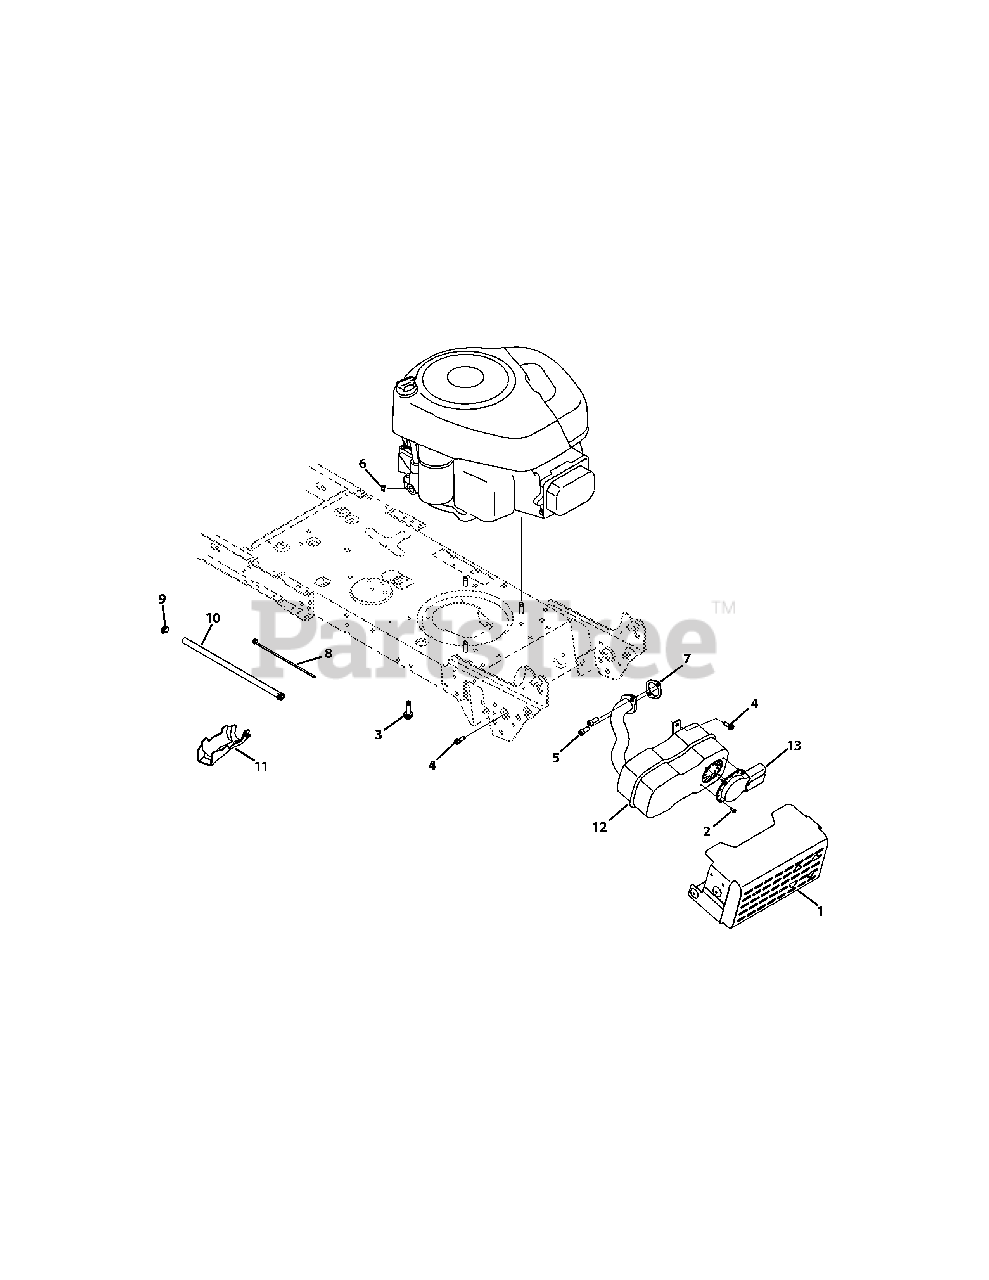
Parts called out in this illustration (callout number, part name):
1	Muffler Shield Assembly with Weld
2	Screw, 8-18 x .500
3	Screw, 3/8-16 x 1.0
4	Screw, 1/4-20 x .750
5	Socket Screw, 5/16-18 x .750
6	Sems Nut, 1/4-20
7	Exhaust Gasket, 10 HP Briggs
8	Cable Tie
9	Clamp Hose, .490 diameter
10	Fuel Hose, Low Permeation
11	Oil Drain Sleeve
12	Muffler, Single Inlet
13	Muffler Deflector Long
